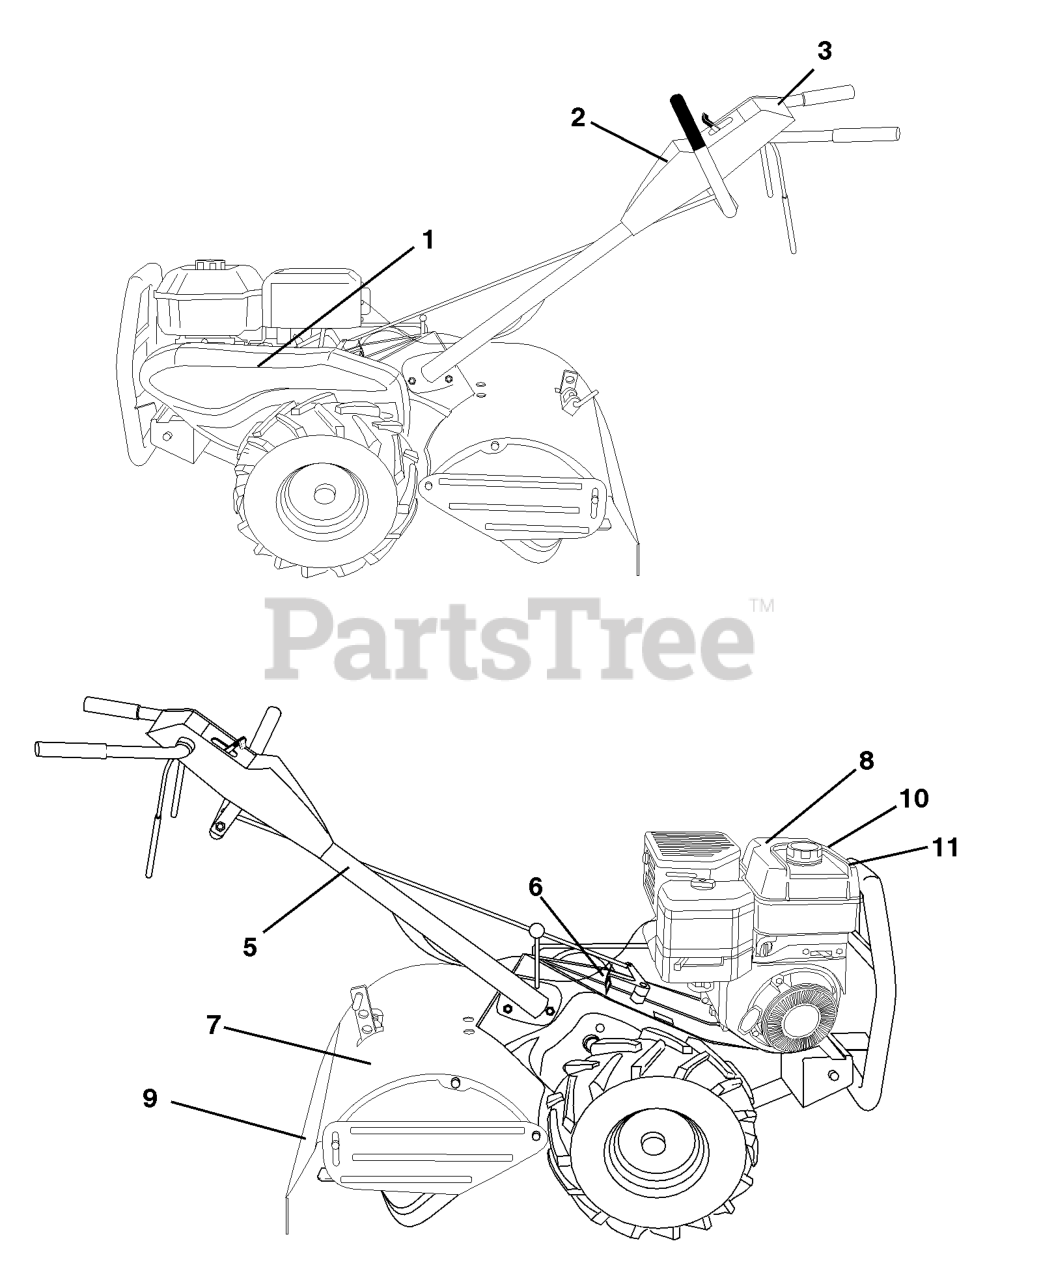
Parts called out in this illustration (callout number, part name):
2	DECAL, LOGO
3	DECAL, LOGO
5	DECAL TI (2 2)
6	DECAL.SHIFT.INDICATOR.TILLER
7	DECAL -CAUTION
8	Decal, Engine HP REF
9	DECAL TI
10	DECAL, ENG. INTEK
11	Decal, Engine Choke/Run REF
